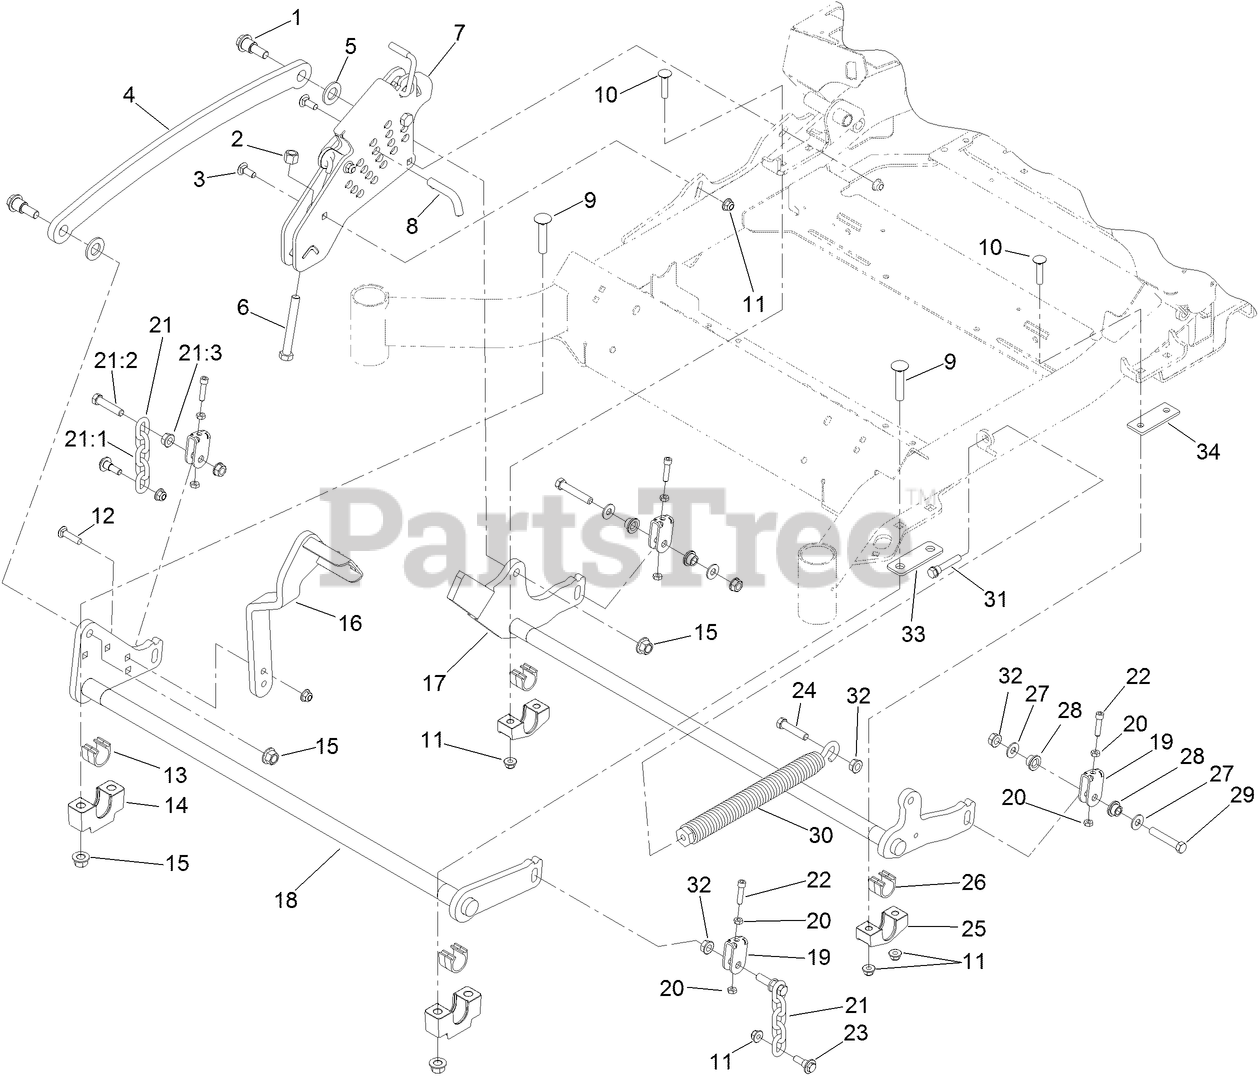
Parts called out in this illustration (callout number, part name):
1	SCREW-SHOULDER, HHF
2	NUT-LOCK, NI
3	BOLT-CARR
4	LINK-LIFT, DECK
5	WASHER-FLAT
6	BOLT-TAP
7	HOC ASM
8	PIN-HOC
9	BOLT-CARR
10	SCREW-CARR
11	NUT-HF, NI
12	SCREW-CARR
13	BEARING-CROSS SHAFT, FRONT
14	SUPPORT-CROSS SHAFT, BEARING
15	NUT-LOCK
16	LEVER-FOOT
17	LIFT-DECK, REAR
18	CROSS SHAFT-FRONT
19	YOKE-ADJUST, DECK
20	NUT-JAM
21	DECK LIFT CHAIN ASM
21:1	CHAIN-LIFT, DECK
21:2	SCREW-HH
21:3	NUT-HF
22	SCREW-HH
23	SCREW-SHOULDER, HHF
24	SCREW-HH
25	SUPPORT-CROSS SHAFT, REAR BEARING
26	BEARING-CROSS SHAFT, REAR
27	WASHER-FLAT
28	BUSHING-FLANGED
29	SCREW-HH
30	SPRING-EXTENSION
31	BOLT-SHOULDER
32	NUT-HF
33	SPACER-DECKLIFT, FRONT
34	SPACER-DECKLIFT, BACK
